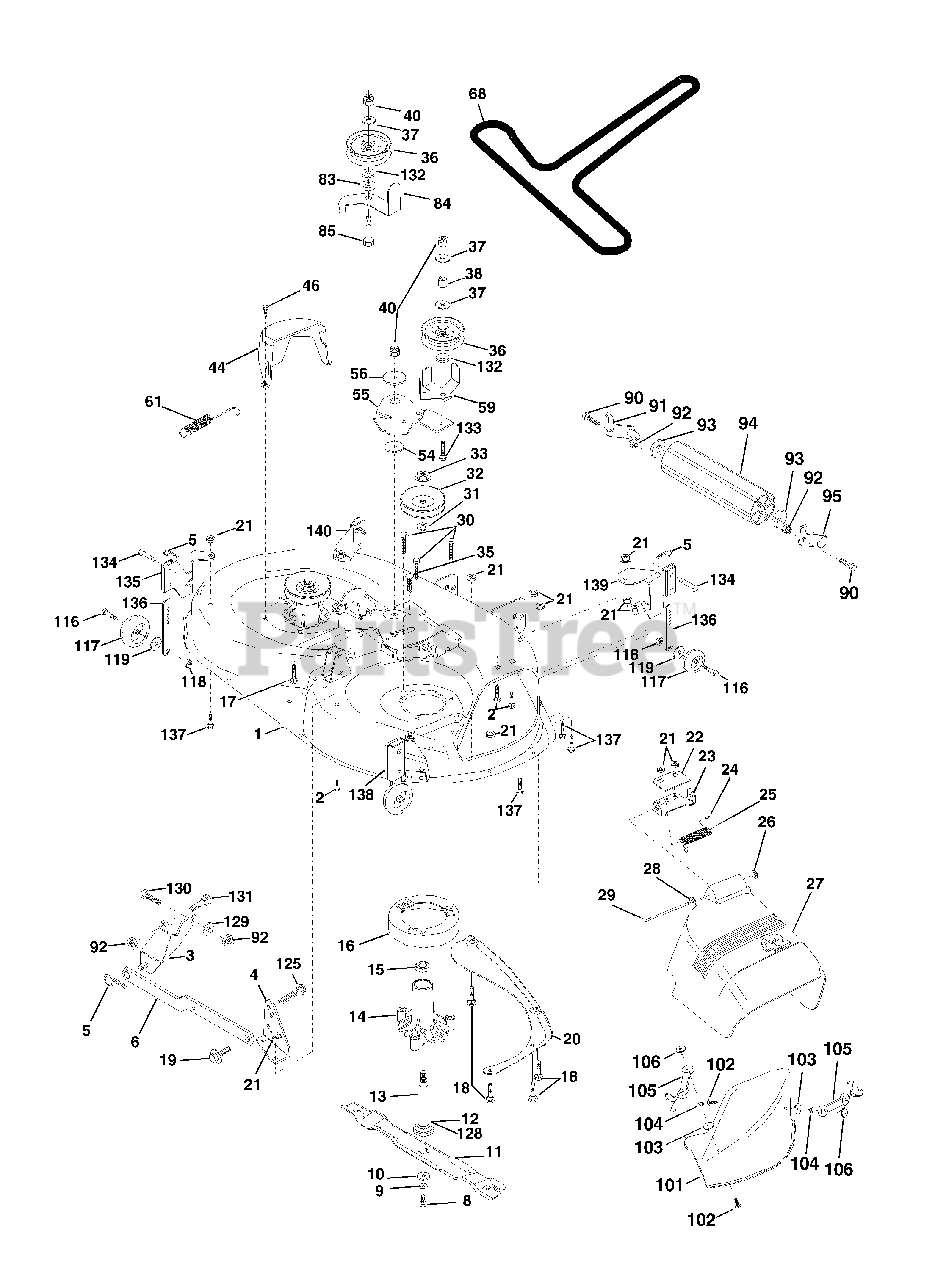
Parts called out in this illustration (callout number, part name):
1	Housing Asm Mower 42"
2	Bolt Rdhd Sqnk 5/16-18unc X3/4
3	Bracket Asm Fr Sway Bar 38/42
4	Bracket Asm Deck 42"sway Bar
5	Retainer Spring
6	Arm Suspension Rear
8	Bolt 3/8-24x1 25 Gr8 Patched
9	Washer Lock Hvy 3/8 Unplated
10	Washer Hard Blade Mower Vented
11	Blade Mower Mulching 42"
12	Bearing Ball #6204 (Mandrel)
13	Shaft Asm W/lower Bearing
14	Housing Mandrel Vented(machd)
15	Bearing Ball Mandrel
16	Stripper Round Mower
17	Bolt Rdhd Sqnk 3/8-16 X 2-1/4
18	Bolt Carr 5/16-18 X 5/8
19	Bolt Shoulder
20	Baffle Vortex 42 Heavy Duty
21	Nut Crown Lock 5/16-18
22	Stiffener Bracket 42"deck
23	Bracket Deflector Mower 42"
24	Cap Sleeve 80x 112 Blk Mower
25	Spring Torsion Deflector 2 52
26	Nut Push Phos & Oil
27	Shield Deflector Mower 42" Blk
28	Washer 11/32 X 5/8 X 16 Ga
29	Rod Hinge 42"6 75 Wlg
30	Screw Thdrol Washer Head
31	Washer Spacer Mower Vented
32	Pulley Mandrel 42"
33	Nut 9/16top Lock Flng Cntr
35	Fastner Christmas Tree
36	Pulley Idler Flat 3 060
37	Washer 13/32 X 13/16 X 16 Ga
38	Spacer Spring Stop Idler
40	Nut Lock 3/8-16 Unc
44	Guard Mandrel LH Black
46	Screw Thdrol 1/4-20x5/8
54	Washer Hardened
55	Arm Idler 42"mower LT/YT
56	Spacer Retainer Pm Mower
59	Guard, Belt
61	Spring Ext. Elect
68	V-Belt Mower
83	Washer Sintered
84	Keeper Belt Idler
85	Bolt Carriage 3/8-16 x 2-1/2 Gr.5
90	Bolt Fin Hex 3/8-16unc X 1
91	Bracket Asm Noseroller LH
92	Nut Lock Hex w/ins. 3/8-16 UNC
93	Washer 17/32 X 7/8 X 16 Ga
94	Roller Nose 38 & 42
95	Bracket Asm Noseroller RH
101	Cover Mulching 42" Blk
102	Screw
103	Washer #10
104	Washer Lock #10
105	Latch Asm Bagger
106	Nut Weld .327/.304 #10-24
116	Bolt Shld
117	Wheel Gauge Donut
118	Nut Centerlock 3/8 - 16 UNC
119	Washer 3/8 x 7/8 x 14 Ga.
125	Cotter Pin
128	Washer Felt
129	Washer 13/32 x 13/16 x 12 Ga.
130	Bolt Fin Hex 3/8-16unc x 1 Gr. 5
131	Bolt Rdhd Sqnk 3/8-16 UNC
132	Washer 13/32 x 1-3/8 x 3 Ga.
133	Bolt Rd Hd 3/8-16 UNC x 2-3/4 Gr.5
134	Pin Head Rivet
135	Bracket Asm Whl Ga. Rear LH 42"
136	Bar Pnt Adjusting Wheel Gauge
137	Bolt Carriage 5/16-18 x 5/8 Short
138	Bracket Asm. Whl Ga. Rear RH 42"
139	Bracket Asm. Whl Ga. Front RH 42"
140	Bracket Asm. Whl Ga. Front LH 42"
